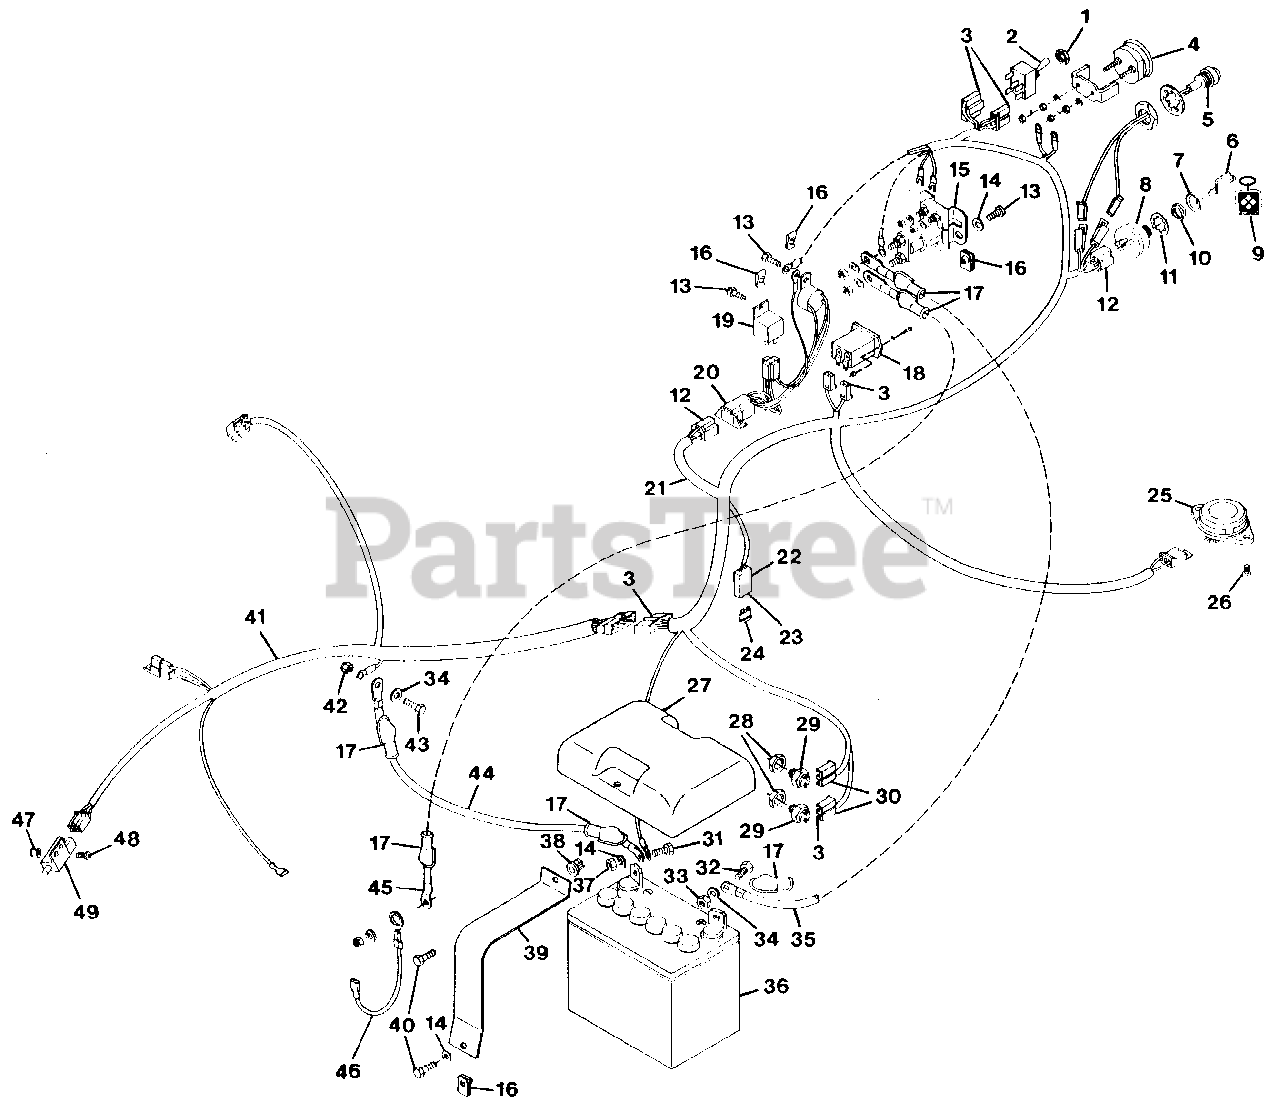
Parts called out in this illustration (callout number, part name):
1	NUT, 1/2-27
2	SWITCH, PTO
3	TERMINAL
4	GAUGE, AMMETER
5	LIGHT, INDICATOR
6	KEY, IGNITION SWITCH
7	BOOT, 9/16 SWITCH
8	SWITCH, IGNITION
9	CHAIN, KEY
10	NUT, JAM 9/16-24
11	WASHER, LOCK 9/16 INT. TOOTH
12	CONNECTOR
13	SCREW, MACHINE 1/4-20 PHD
14	WASHER, FLAT .281X.625X.065
15	SWITCH, MAGNETIC
16	NUT, SPEED 1/4-20
17	BOOT, BATTERY CABLE
18	HOURMETER
19	RELAY
20	MODULE, TIME DELAY
21	HARNESS, WIRING
22	CONNECTOR
23	TERMINAL, 14-16 GAUGE
24	FUSE, 25 AMP
25	SWITCH, SEAT
26	SCREW, MACHINE 1/4-20
27	COVER, BATTERY
28	NUT, STAMPED 9/16-18
29	SWITCH, INTERLOCK
30	CONNECTOR, 2-WIRE SWITCH
31	BOLT, HEX 1/4-20-X.625
32	BOLT, HEX 5/16-18X.625
33	NUT, HEX 5/16-18
34	WASHER, FLAT .344X.688X.065
35	CABLE, BATTERY TO SOLENOID
36	BATTERY, 12 VOLT
37	NUT, HEX 1/4-20
38	GROMMET, PLASTIC
39	STRAP, BATTERY
40	SCREW, 1/4-20X.50 SELF TAPPING
41	HARNESS, WIRING KOHLER
41	HARNESS, WIRING ONAN
42	NUT, LOCK 5/16-18
43	BOLT, HEX 5/16-18X1.00
44	CABLE, NEGATIVE BATTERY
45	ASSEMBLY, CABLE
46	ASSEMBLY, CABLE
47	NUT, LOCK 10-24
48	SCREW, MACHINE 10-24X.625 PHD
49	SWITCH, INTERLOCK
